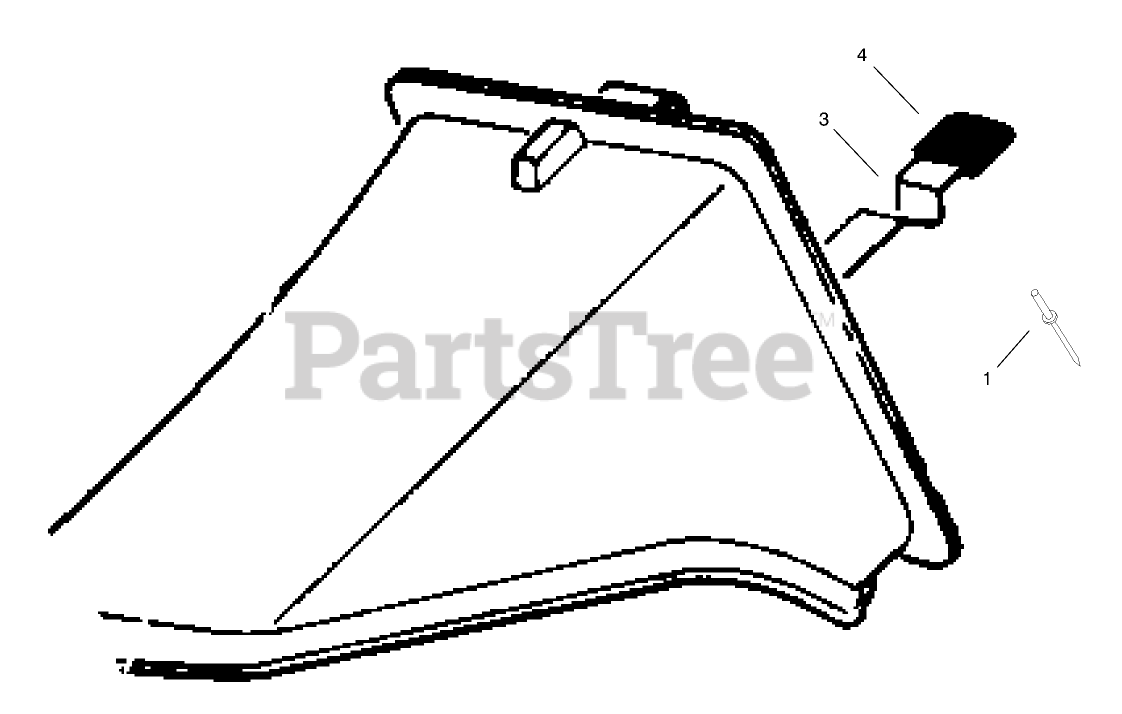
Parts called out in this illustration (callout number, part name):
1	RIVET-HEAD, FLAT
3	LATCH-PLUG, DISCHARGE
4	GRIP-LATCH
